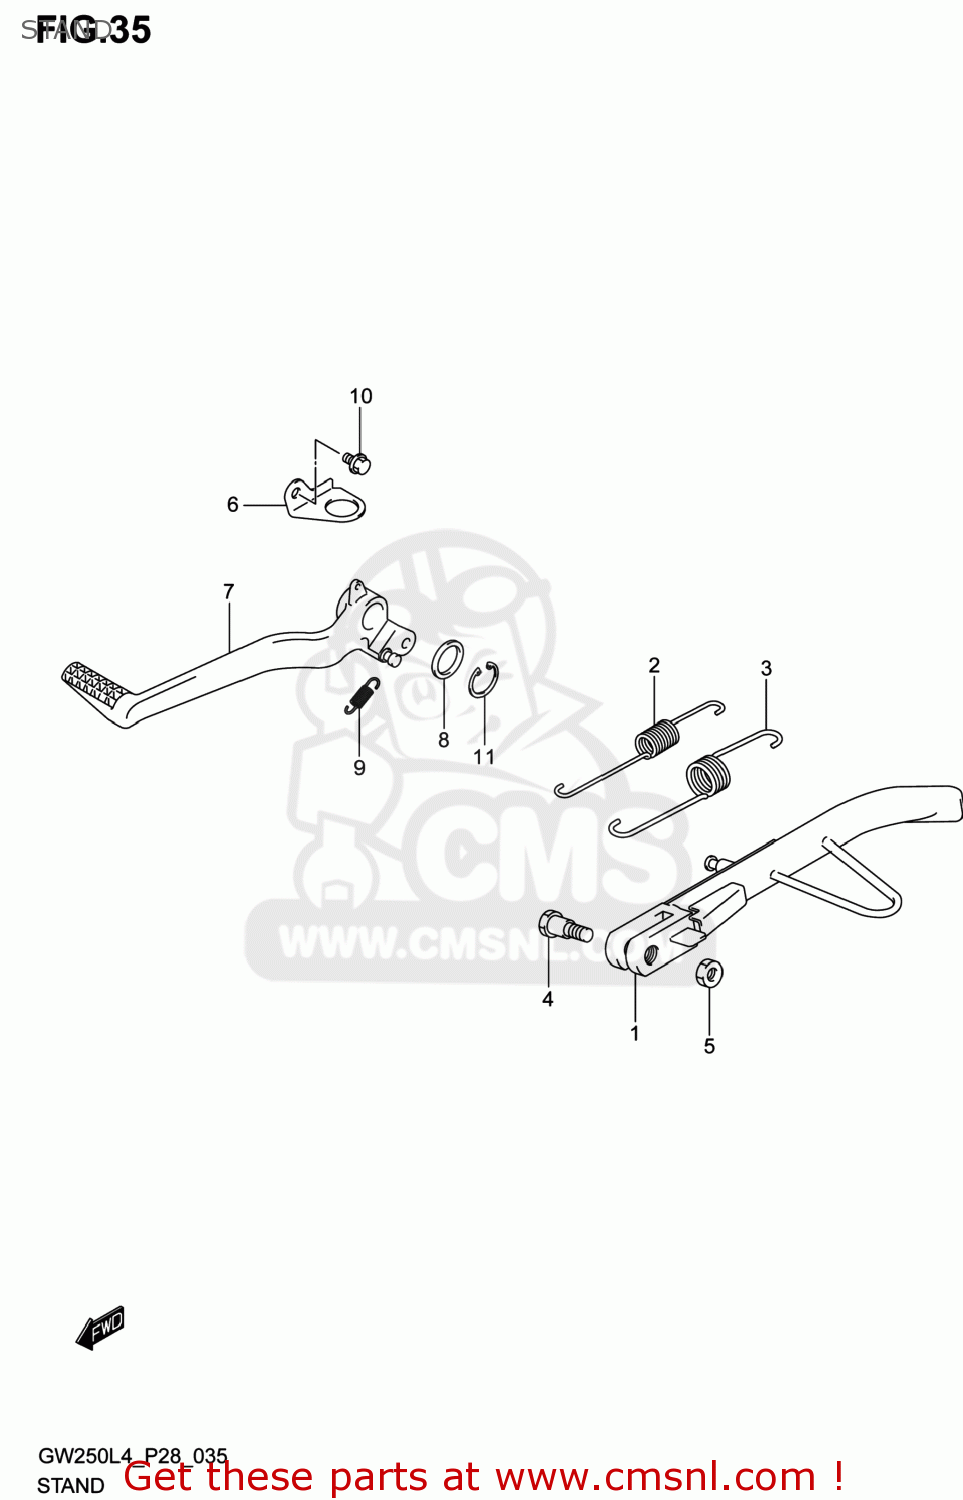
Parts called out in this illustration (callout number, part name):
1	STAND,PROP
2	SPRING,PROP STAND
3	SPRING,PROP STAND OUTER
4	BOLT(10X38)
5	NUT
6	BRACKET,STOP LAMP SWITCH
7	PEDAL,BRAKE
8	WASHER(18X24X1)
9	SPRING
10	BOLT
11	CIRCLIP
